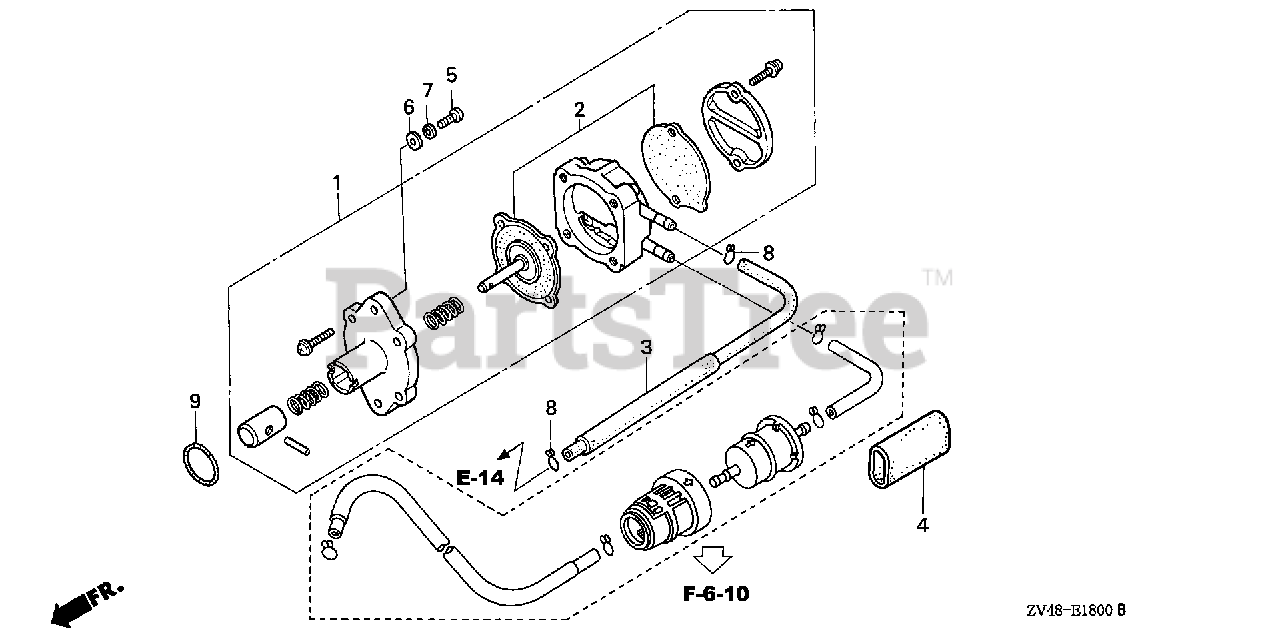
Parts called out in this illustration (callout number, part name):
1	PUMP ASSY., FUEL
3	TUBE, FUEL (A)
4	PROTECTOR, TUBE
5	SCREW, PAN (6X22)
6	WASHER, PLAIN (6.2MM)
7	WASHER, SPRING (6MM)
8	CLIP, TUBE (B10)
9	O-RING (20.8X2.4)
